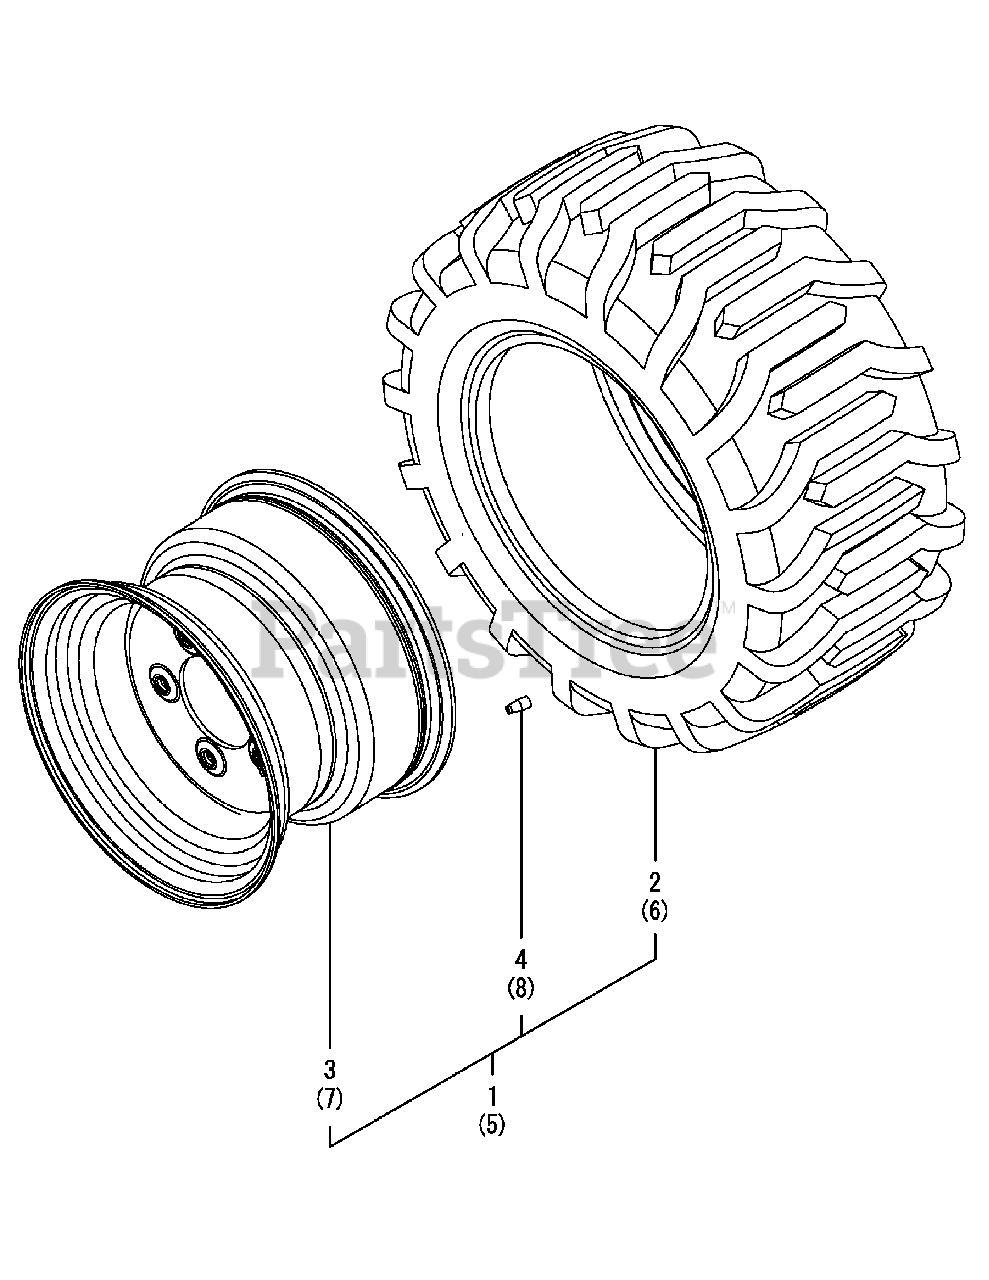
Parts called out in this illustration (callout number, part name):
1	R4 FRONT TIRE L KIT
2	TIRE,18X8.5-10 R4
5	R4 FRONT TIRE R KIT
6	TIRE,18X8.5-10 R4
